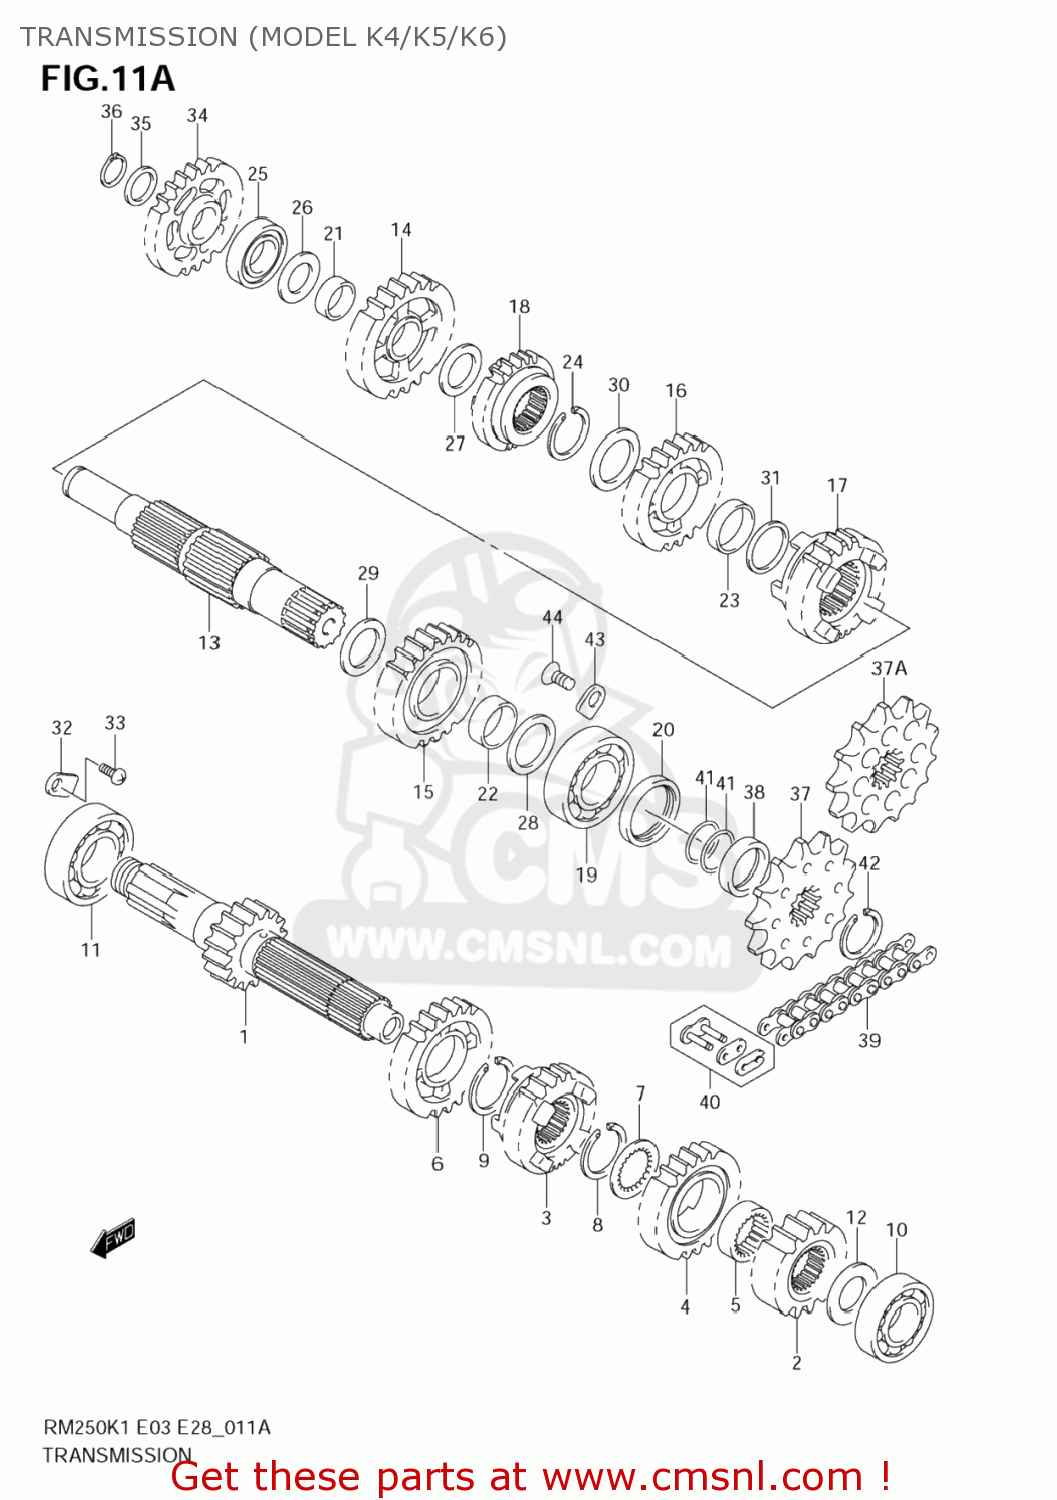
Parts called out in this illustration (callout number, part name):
1	SHAFT,COUNTER(NT:15)
2	GEAR,2ND DRIVE(NT:17)
3	GEAR,3RD DRIVE
4	GEAR,4TH DRIVE(NT:21)
5	BUSH,4TH DRIVE GEAR
6	GEAR,5TH DRIVE(NT:23)
7	WASHER,LOCK
8	CIRCLIP
9	CIRCLIP
10	BEARING
11	BEARING
12	SHIM(17X30X1)
13	SHAFT,DRIVE
14	GEAR,1ST DRIVEN(NT:27)
15	GEAR,2ND DRIVEN(NT:25)
16	GEAR,3RD DRIVEN(NT:23)
17	GEAR,4TH DRIVEN(NT:21)
18	GEAR,5TH DRIVEN(NT:20)
19	BEARING(22X56X15)
20	SEAL,OIL(28X38X7.5)
21	BUSH(20X24X10)
22	BUSH(25X28X10)
23	BUSH(25X28X10)
24	CIRCLIP
25	BEARING(17X40X12)
26	SHIM(17X30X1)
27	SHIM(20X30X1)
28	SHIM(22X34X1.5)
29	SHIM(25X34X1)
30	SHIM(25X34X1)
31	SHIM
32	RETAINER
33	SCREW
34	GEAR,KICK STARTER IDLE(NT:27)
35	SHIM(17X24X0.5)
36	CIRCLIP,17MM
37	SPROCKET,ENGINE (NT:13)
37A	SPROCKET,ENGINE(NT:13)
38	SPACER,ENGINE SPROCKET
39	CHAIN ASSY,DRI
40	JOINT SET,CHAIN
41	O RING(D:1.9,ID:19.8)
42	CIRCLIP
43	RETAINER,COUNTER BEARING,R
44	SCREW
